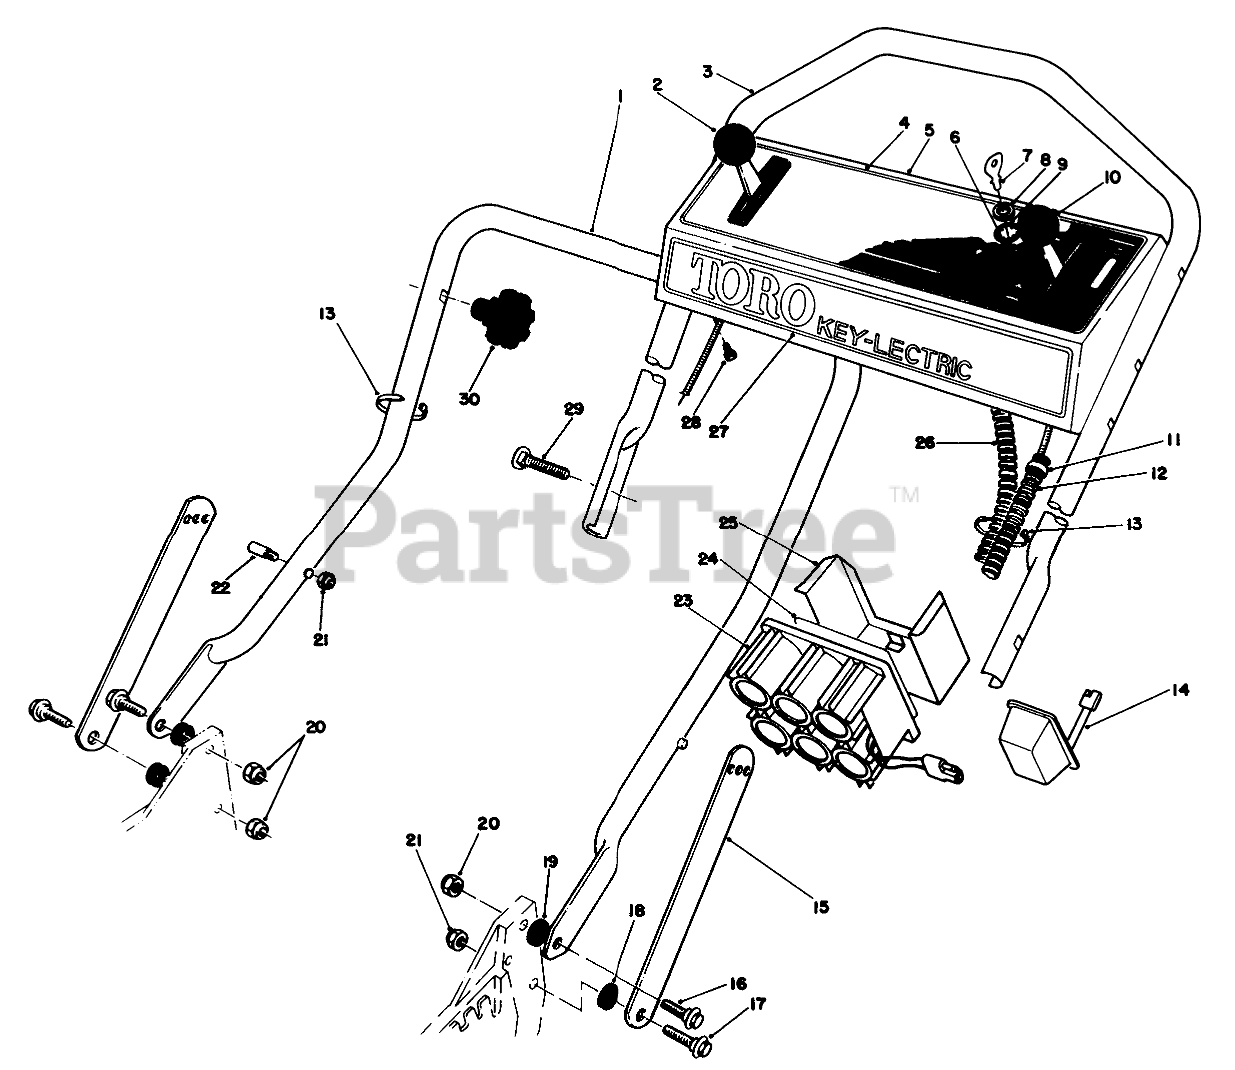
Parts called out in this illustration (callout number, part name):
1	LOWER HANDLE ASM
2	SERVICE THROTTLE CONTRO
3	Handle-Upper
4	INST PANEL DECAL
5	Panel-Control (Incl. Ref. #4)
6	Switch-Starter (Incl. Ref. #8-9)
7	Key
8	NUT-HH
9	WASHER-TOOTH, INTERNAL
10	SERVICE TRACT. CONTROL
11	FITTING-RING
12	CONTROL CABLE COVER
13	TIE-CABLE
14	Charger
15	Handle Latch
16	SCREW-SHOULDER
17	SCREW-SHOULDER
18	SPACER
19	SPACER
20	NUT-LOCK, NI
21	NUT-LOCK, NI
22	HANDLE PIN
23	BATTERY ASSEMBLY
24	Decal
25	Retainer-Battery
26	WIRE HARNESS
27	Decal-Toro
28	SCREW-HWHTF
29	5/16-18 X 2 HNDLE SCREW
